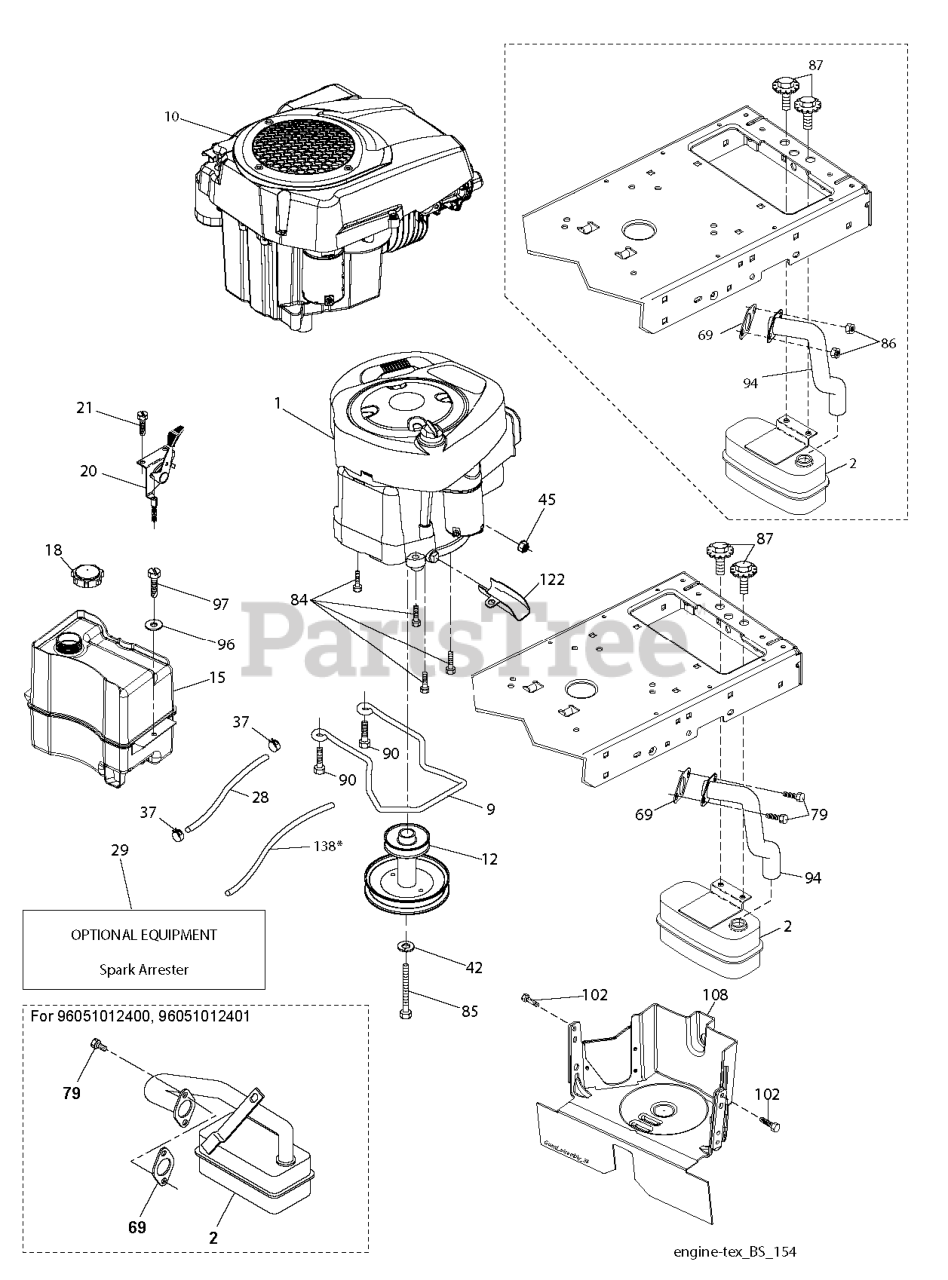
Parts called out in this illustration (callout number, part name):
2	MUFFLER.ASM.SNGL.XTNDED.DFLCTR
2	MUFFLER.SINGLE.CYL.KOHL/B&S
2	MUFFLER.ASM.SINGLE
2	MUFFLER.LT.BRIGGS.14HP.IC/OHV
9	KEEPER.BELT.ENG.4.25"2.BLT.431
9	Keepers
12	ENGINE.PULLEY
15	FUEL.TANK.ASM.NON-EPA
15	Tanks
18	CAP ASM.FUEL.2.25"FR.
20	THROTTLE.COBRA.21".RSTART.BLK
20	CONTROL.TH/CK.C.
28	LINE.FUEL.20
28	LINE.FUEL.20"FRONT.EMI
29	KIT.SPARK ARRESTOR 794945 B&S
37	HOSE CLAMP
45	Hardware
45	NUT
45	NUT HEXAGON WITH FLANGE, SERRA
69	GASKET GASKET.EXHAUST.LONCIN 3
69	REPL BY 532 27 22-93
84	SCREW 3/8-16X1
84	SCREW.3/8-16
85	BOLT.HEX.7/16-20X4.GR5.1.5BLUE
86	NUT.HEX.FLANGE.TOPLOCK
87	BOLT.5/16-18UNCX3/4 W/SEMS.BLK
90	SCREW 3/8-16X1
94	EXHAUST.TUBE.B&S.28/31
94	TUBE TUBE.EXHAUST.LONCIN 452.T
97	SCREW HEXWSHR 1/4-20X3/4
108	COVER ENGINE PULLEY COVER WITH
122	EXTENSION DRAIN OIL
